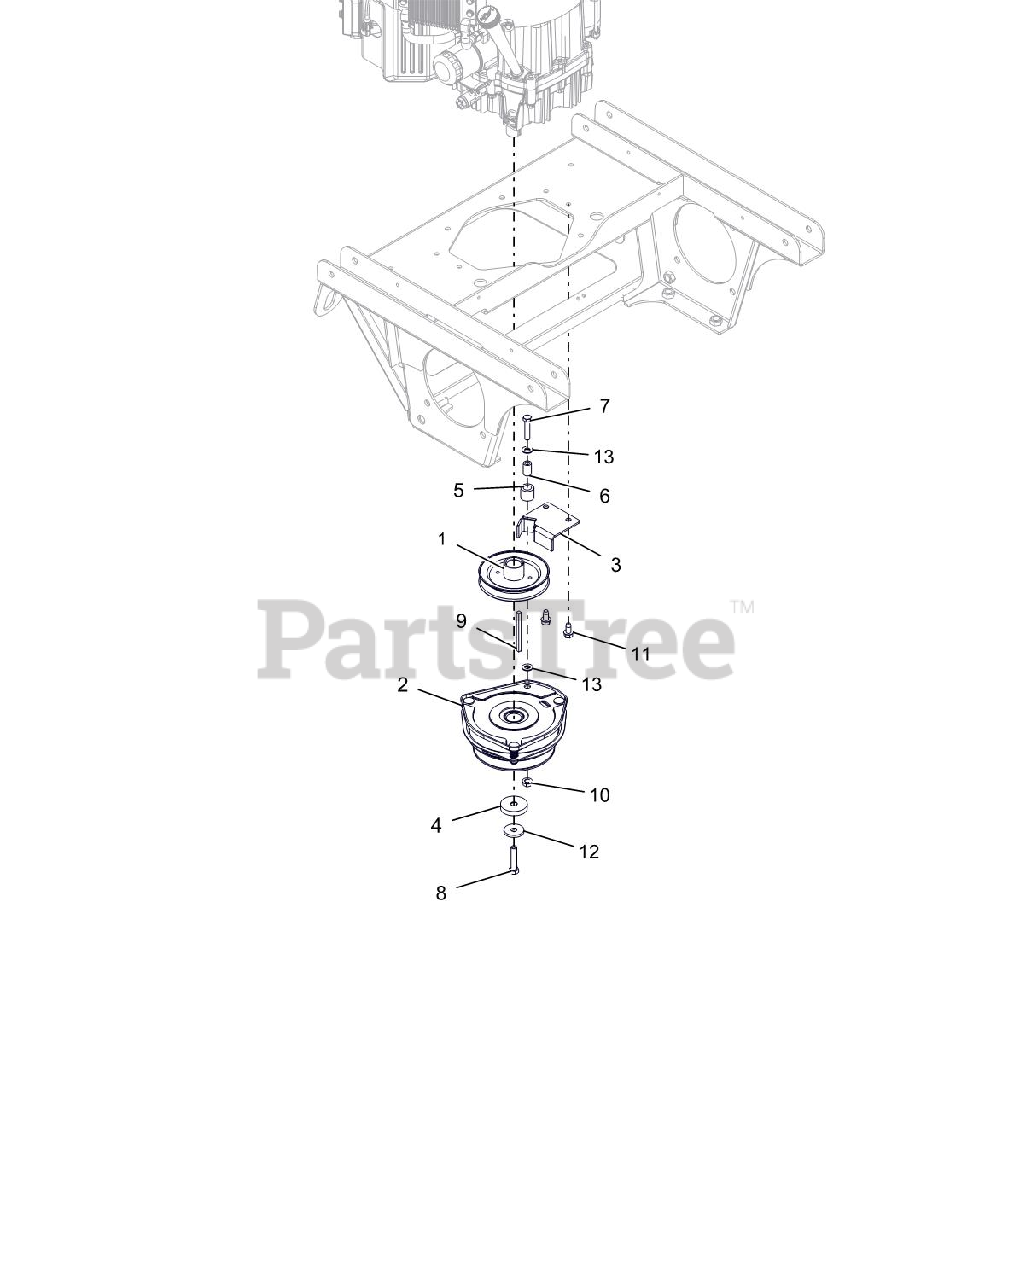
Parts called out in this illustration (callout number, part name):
1	SHEAVE-ENGINE 1.127ID X 5.25OD
2	CLUTCH, ELE-OGURA GT3.5-VP01R
3	CLUTCH STOP WLDMT - BLACK
4	SPACER, .450X2.00X.396
5	BUMPER,RUBBER .62X1.0X.88 LG
6	BUSH.,S.391X.622X.950 ST
7	@BLT-HEX .38-16X1.75 GR5 YWZC
8	BLT-HEX .438-20X2 G8YZ NYTORQ
9	KEY-SQ. .25X3.50X.25 SAE
10	@NUT-LK-TOP-FLG .38-16 YWZC
11	@SCR-TAP .38-16X.75 HWH TR YWZ
12	WASHER, 7/16" SPRING DISK
13	@WSHR-FL-STL.406X.812X.065 YWZ
